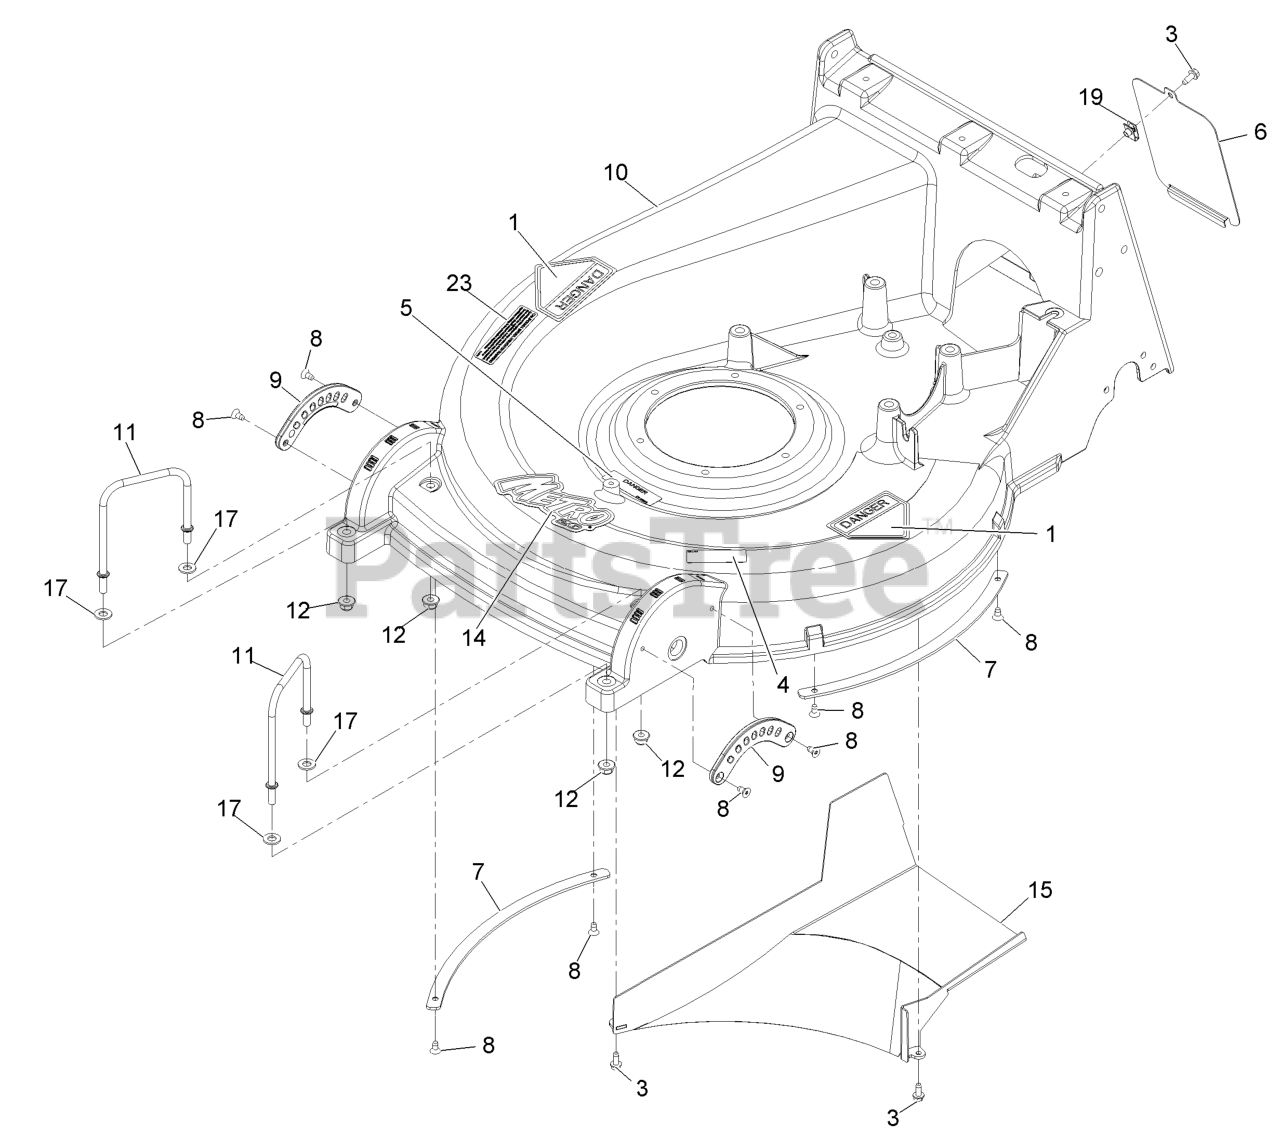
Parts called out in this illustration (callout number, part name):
1	DECAL-DANGER
3	SCREW-HWH
4	DECAL-BLADE
5	DECAL-COVER, MISSING
6	COVER-ACCESS, AXLE
7	PLATE-SKID, 10 GAGE
9	QUADRANT-FRONT
10	ASM,DECK M26 W/DECALS
12	NUT-HF, NI
14	DECAL,METRO 26
15	CHUTE ASM
17	WASHER-FLAT
19	Nut-Retainer-Panel 1/4-20
23	DECAL-ARRESTER, SPARK
